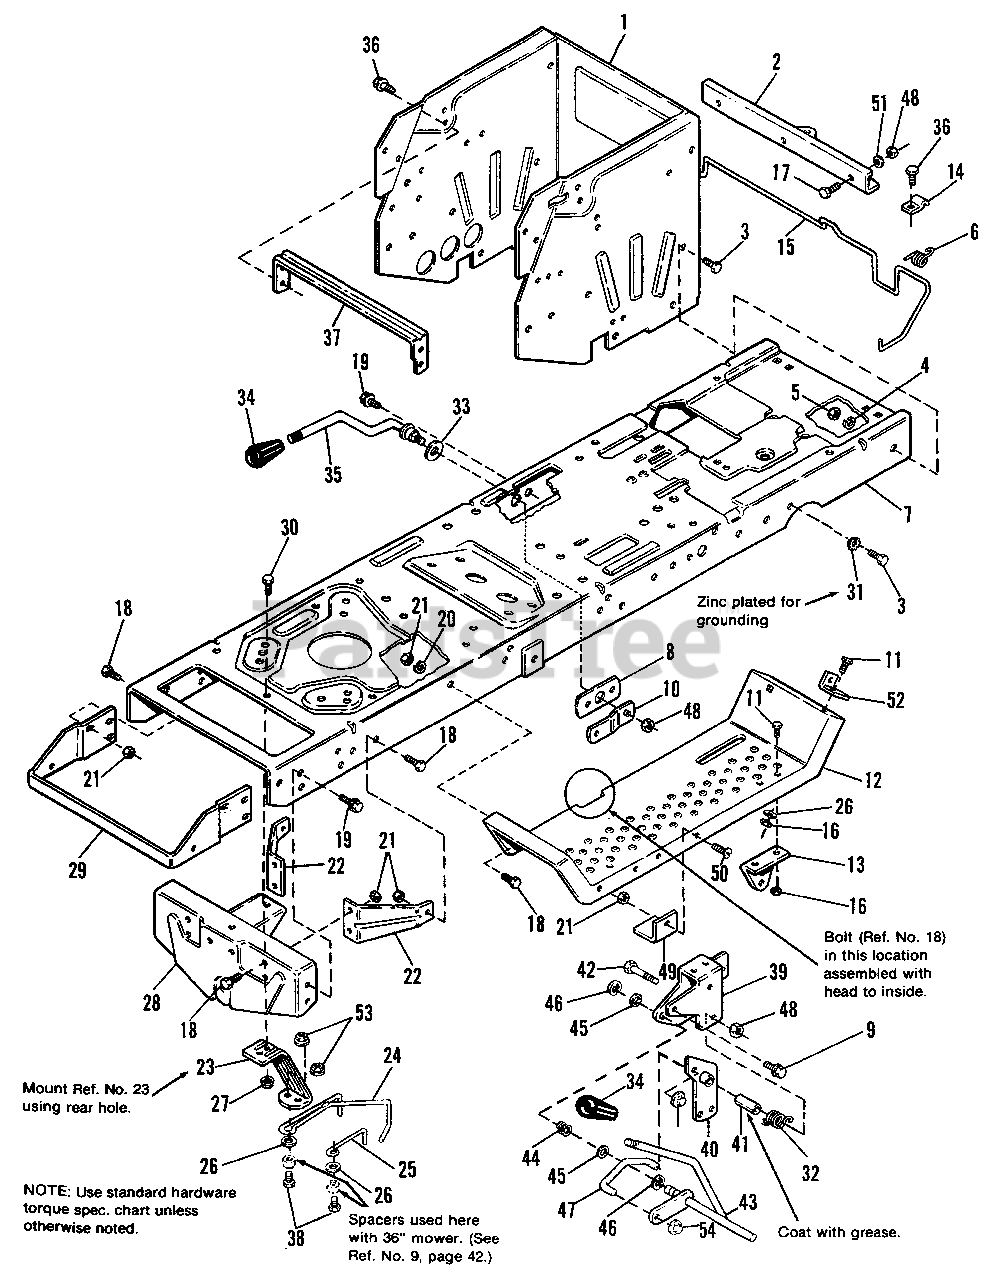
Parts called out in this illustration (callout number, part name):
1	SUPPORT, Axle, Wrapper
2	BAR, Draw
3	CAPSCREW, Hex Hd., 3/8-16 x 1
4	LOCKWASHER, 3/8, Zinc Pltd.
5	NUT, Hex, Full, 3/8-16 (Zinc pltd.)
6	SPRING, Torsion
8	BAR, Support
9	SCREW, Taptite, 1/4-20 x 1/2
10	ARM, Support
11	CAPSCREW, Hex Hd., 1/4-20 x 5/8
13	SUPPORT, Clutch
15	LATCH, Seat
16	NUT, Hex, 1/4-20
17	CAPSCREW, 3/8-16 x 3/4
18	CAPSCREW, Hex Hd., 5/16-18 x 3/4
19	SCREW, Hex Taptite, 5/16-18 x 3/4
20	LOCKWASHER, 5/16
21	NUT, Hex, Full, 5/16-18
22	BRACE, Axle Support
26	WASHER, Plain, 1/4
27	NUT, Flange, Whizlock 5/16-18
28	SUPPORT, Axle
29	SUPPORT, Hood
30	SCREW, Hex Hd., Flange, Whizlock, 5/16-18 x 1-1/4
31	LOCKWASHER, Ext. 3/8, Zinc Pltd.
34	GRIP
35	HANDLE, Lift
36	SCREW, Hex, Washer Hd., Taptite, 5/16-18 x 1/2
37	BRACE, Seat
38	CAPSCREW, 5/16-18 x 1-1/2
39	BRACKET, P.T.O.
40	ARM ASSY., P.T.O. Rod
42	CAPSCREW, Hex Hd., 3/8-16 x 2/1-4
43	HANDLE ASSY., P.T.O.
45	WASHER on P.T.O. Link
46	RING, Snap
47	LINK, P.T.O.
48	NUT, Hex, 3/8-16
49	UP-STOP, Mower
50	SCREW, Truss Hd., Slotted, 5/16-18 x 3/4
51	LOCKWASHER, 3/8
52	BRACKET, Seat Latch
53	NUT, Lock, Flange 5/16-18
54	PALNUT, 3/8
